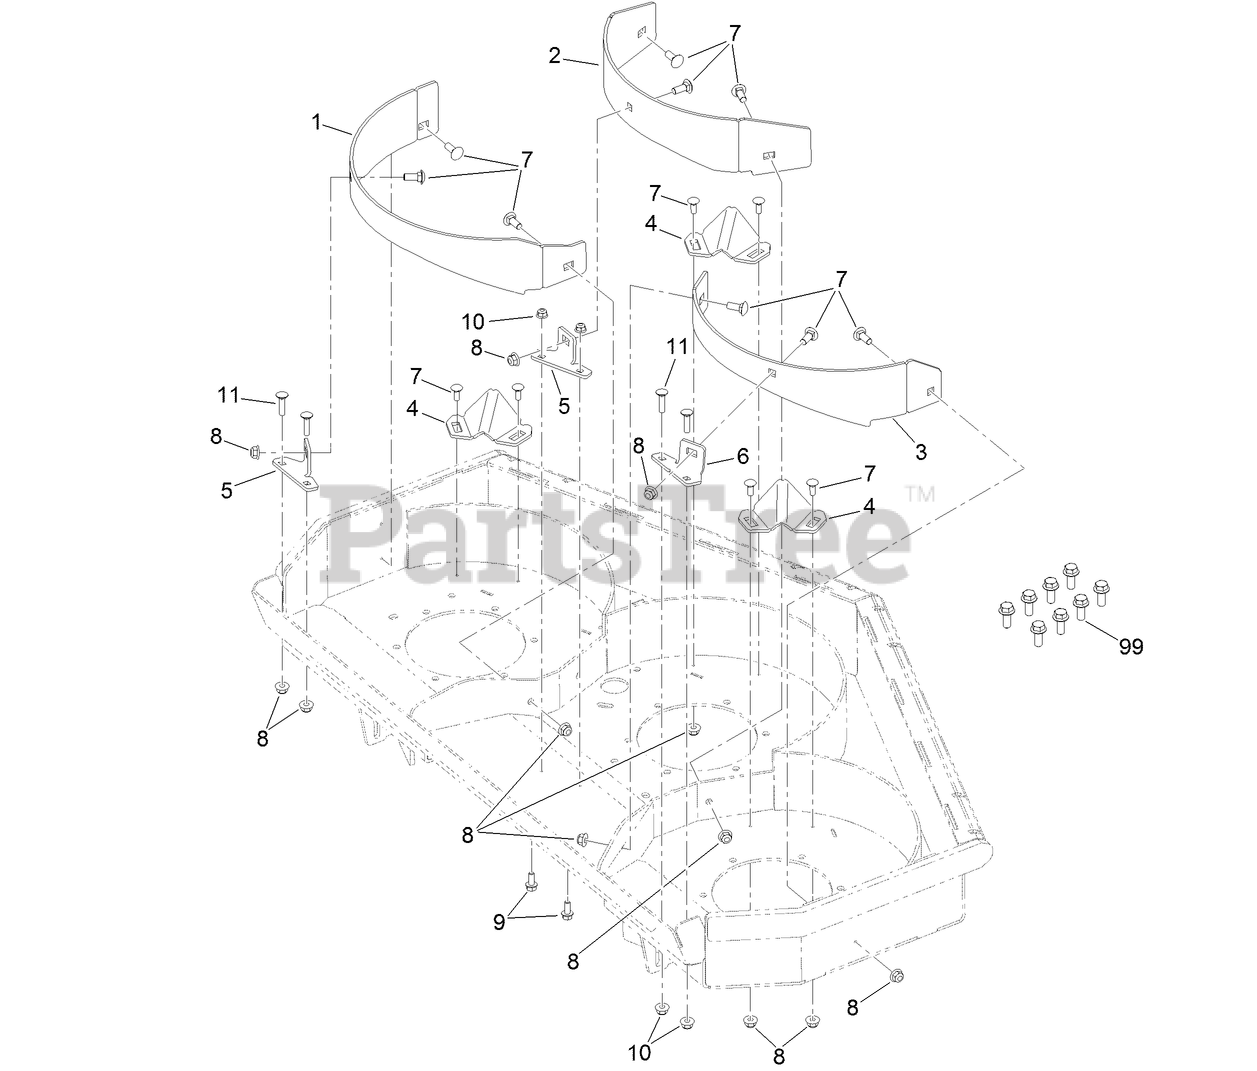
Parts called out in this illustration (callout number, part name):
1	BAFFLE-RH
2	BAFFLE-CENTER
3	BAFFLE-LH
5	SUPPORT-BAFFLE
6	SUPPORT-BAFFLE RIGHT, LH
7	BOLT-CARR
8	NUT-HF, NI
9	SCREW-HHF
10	NUT-HF, NI
11	SCREW-CARR
99	SCREW-HHF
